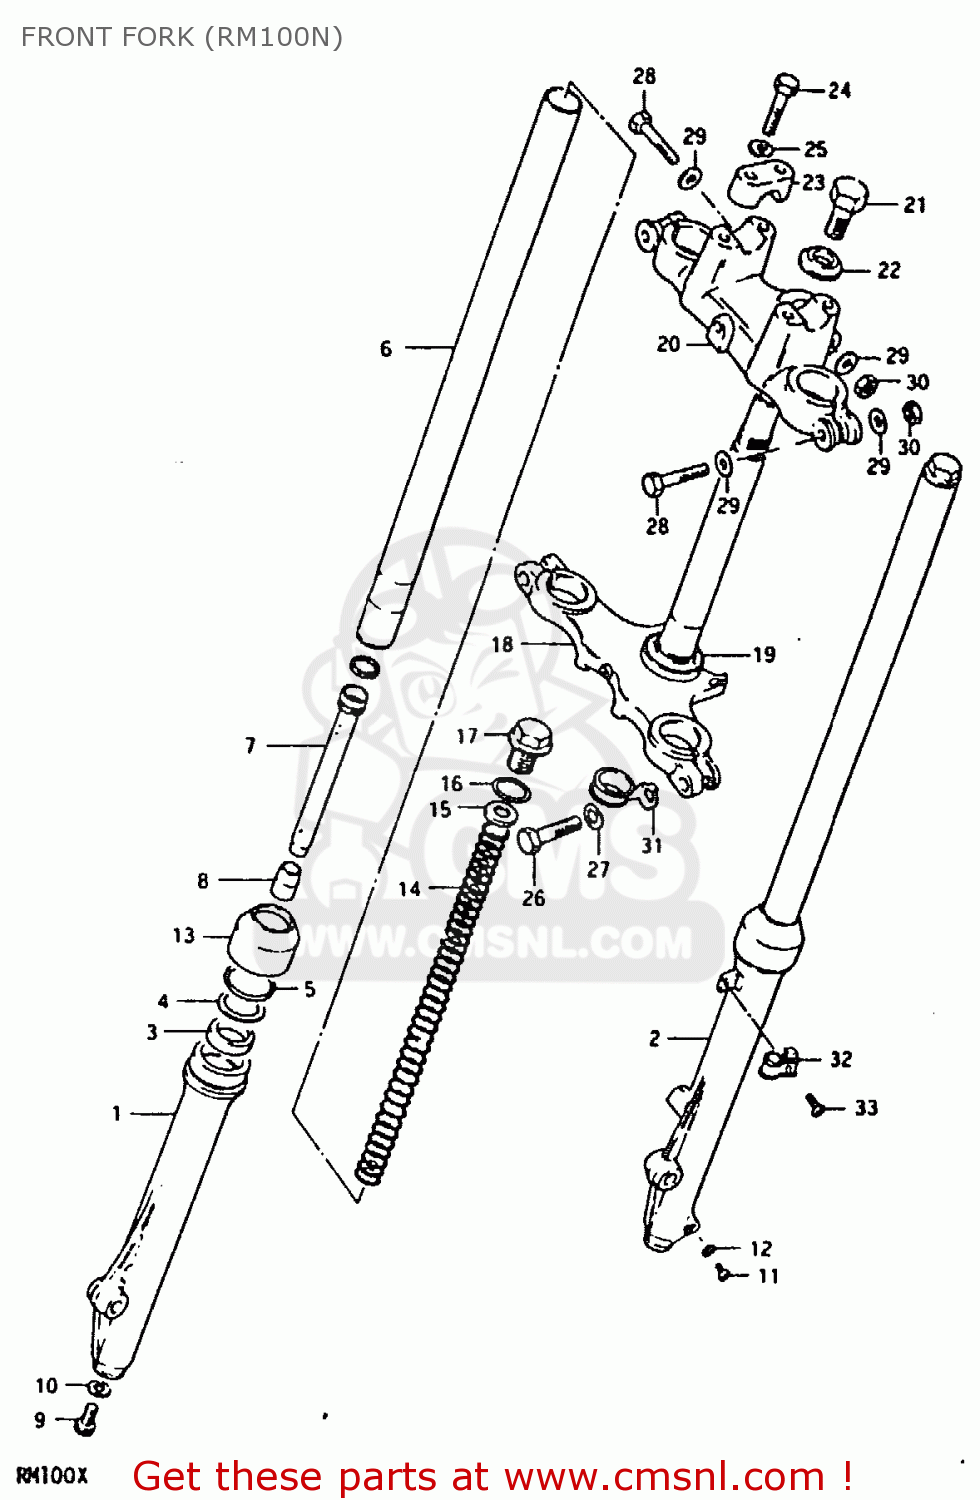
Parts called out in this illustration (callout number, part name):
1	TUBE,OUTER,RIGHT
2	TUBE,OUTER,LEFT
3	SEAL,OIL
4	RING,FORK BACK UP
5	CIRCLIP,FORK OIL SEAL
6	TUBE,FORK,INNER
7	CYLINDER,FRONT FORK
8	PIECE,OIL LOCK
9	BOLT,FORK CYLINDER(10X25)
10	GASKET (NAS)
11	SCREW
12	GASKET,DRAIN,PLUG (NAS)
13	SEAL,DUST
14	SPRING
15	GUIDE,FRONT FORK SPRING C
16	O RING
17	CAP,FORK INNER TUBE
18	STEM,STEERING
19	RACE,STEERING,OUTER,UPPER
20	HEAD,STEERING STEM
21	BOLT
22	WASHER
23	HOLDER,HANDLEBAR
24	BOLT
25	LOCK WASHER
26	BOLT
27	WASHER,LOCK 12
28	BOLT 8X55
29	WASHER
30	NUT 8MM
31	GUIDE,CABLE
32	CLIP,CABLE
33	SCREW
